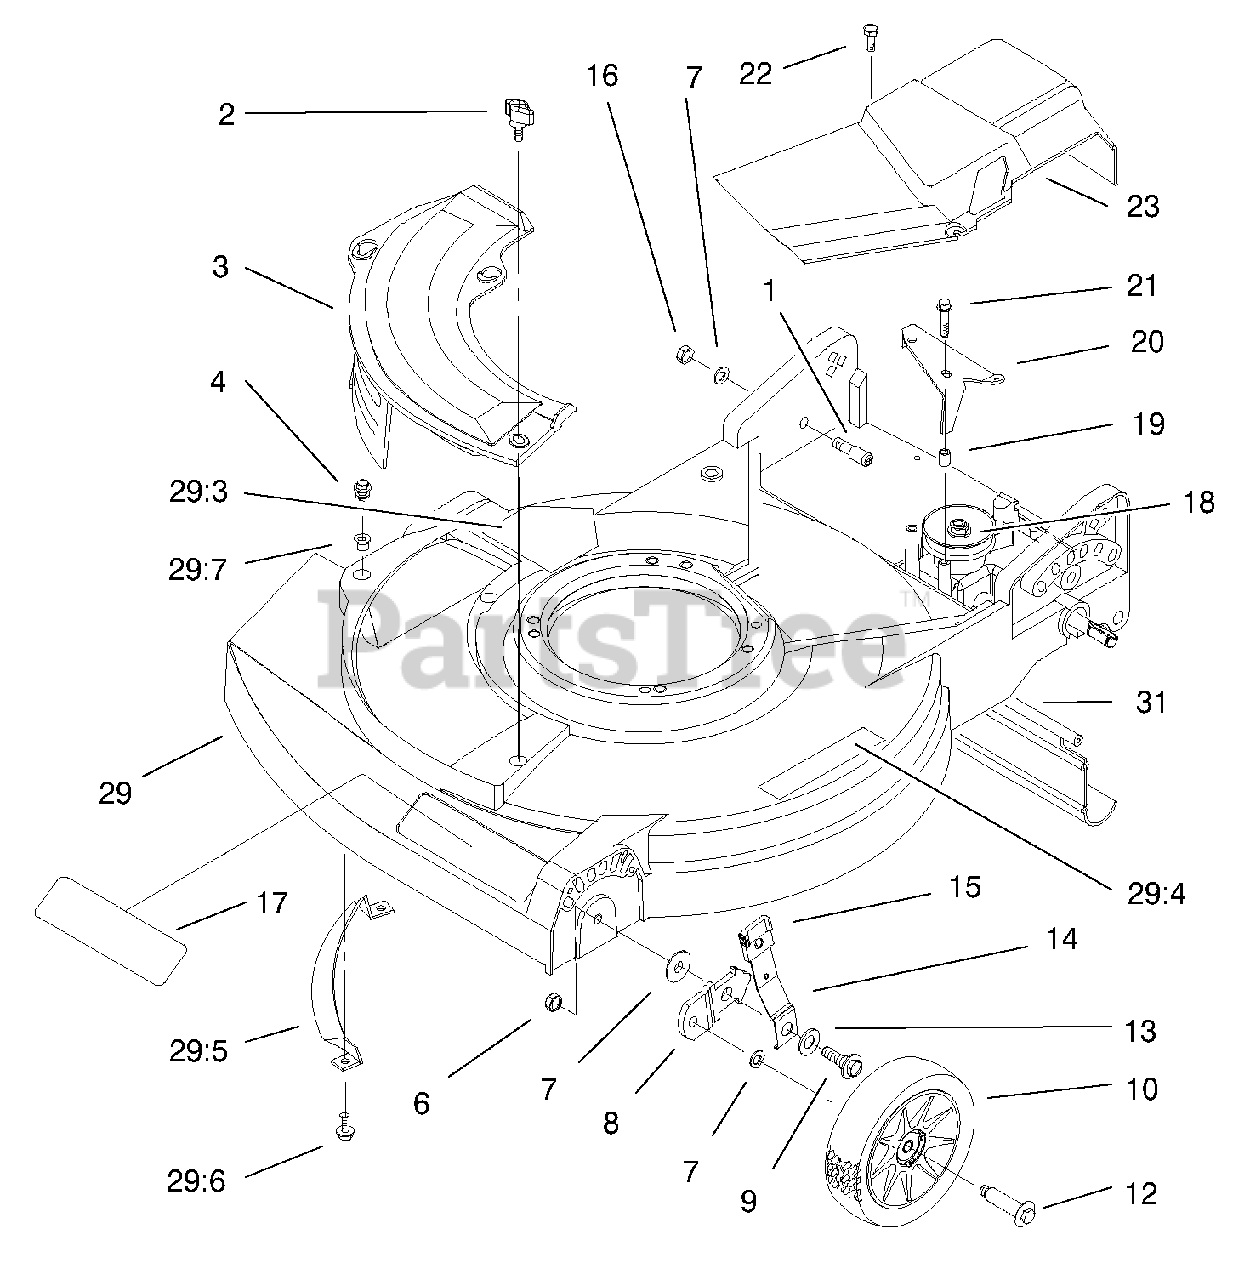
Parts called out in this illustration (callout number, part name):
1	Screw-Torx
3	Plate-Mulch
4	Screw-Sems
6	Nut-Lock, NI
8	Bracket-Wheel Height Adjustment
9	Bolt-Shoulder
10	Wheel & Tire ASM
12	Bolt-Shoulder
13	Washer-Belleville
14	Spring Arm ASM-Front
15	Knob-Lever, Height Adjustment
17	Decal-Deck
18	Gear Case ASM
20	Bracket-Actuator
21	Screw-HWH
23	Cover-Drive
29:3	Decal-Danger
29:4	Decal-Warning
29:5	Toe Bar
29:6	Screw-HWH
29:7	Grommet-Plastic
31	Shield-Trailing
